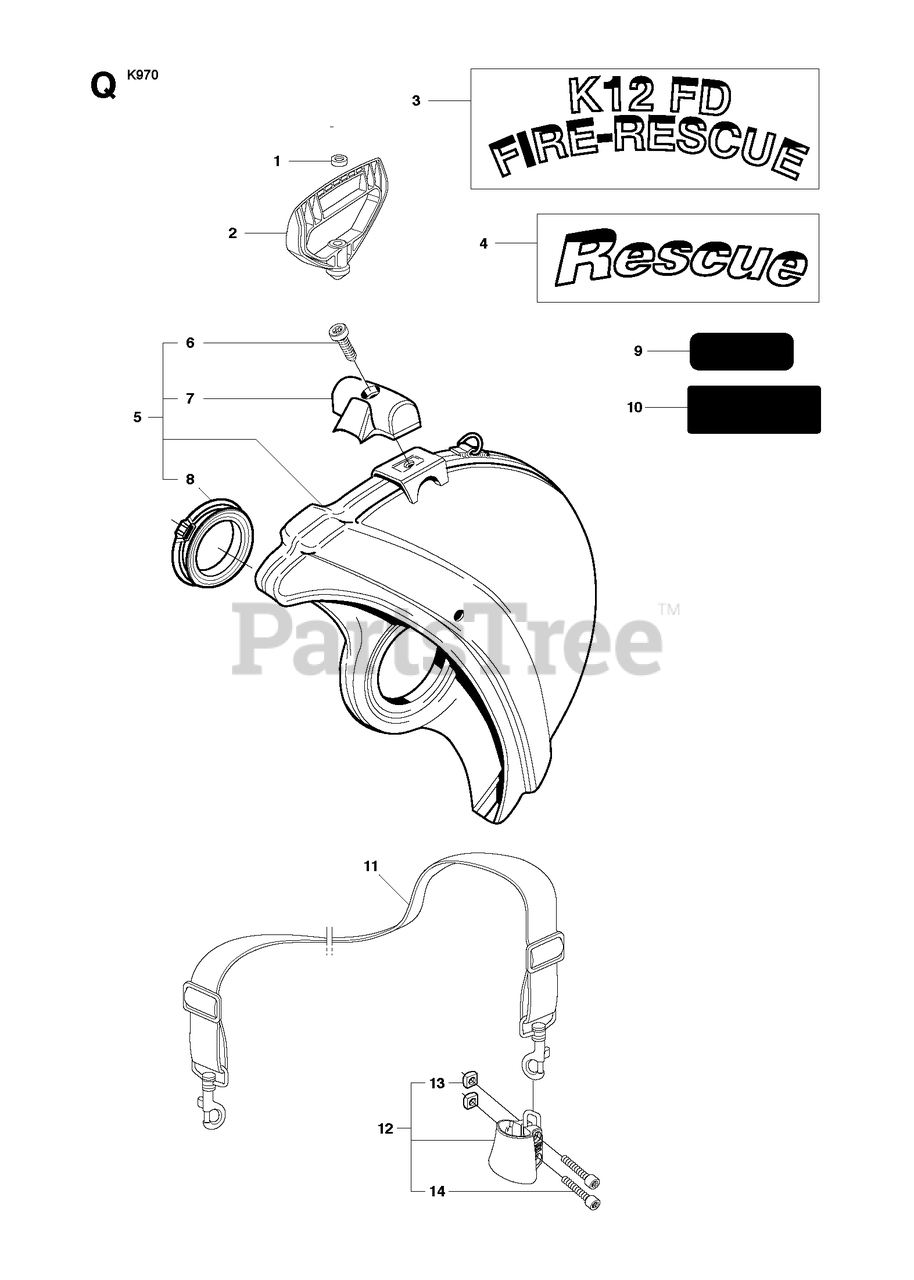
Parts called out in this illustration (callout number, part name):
2	STARTER HANDLE
5	BLADE GUARD14"
5	BLADE GUARD12"
6	SCREW ITXSCM
11	SHOULDER STRAP
14	SCREW ITXSCM
